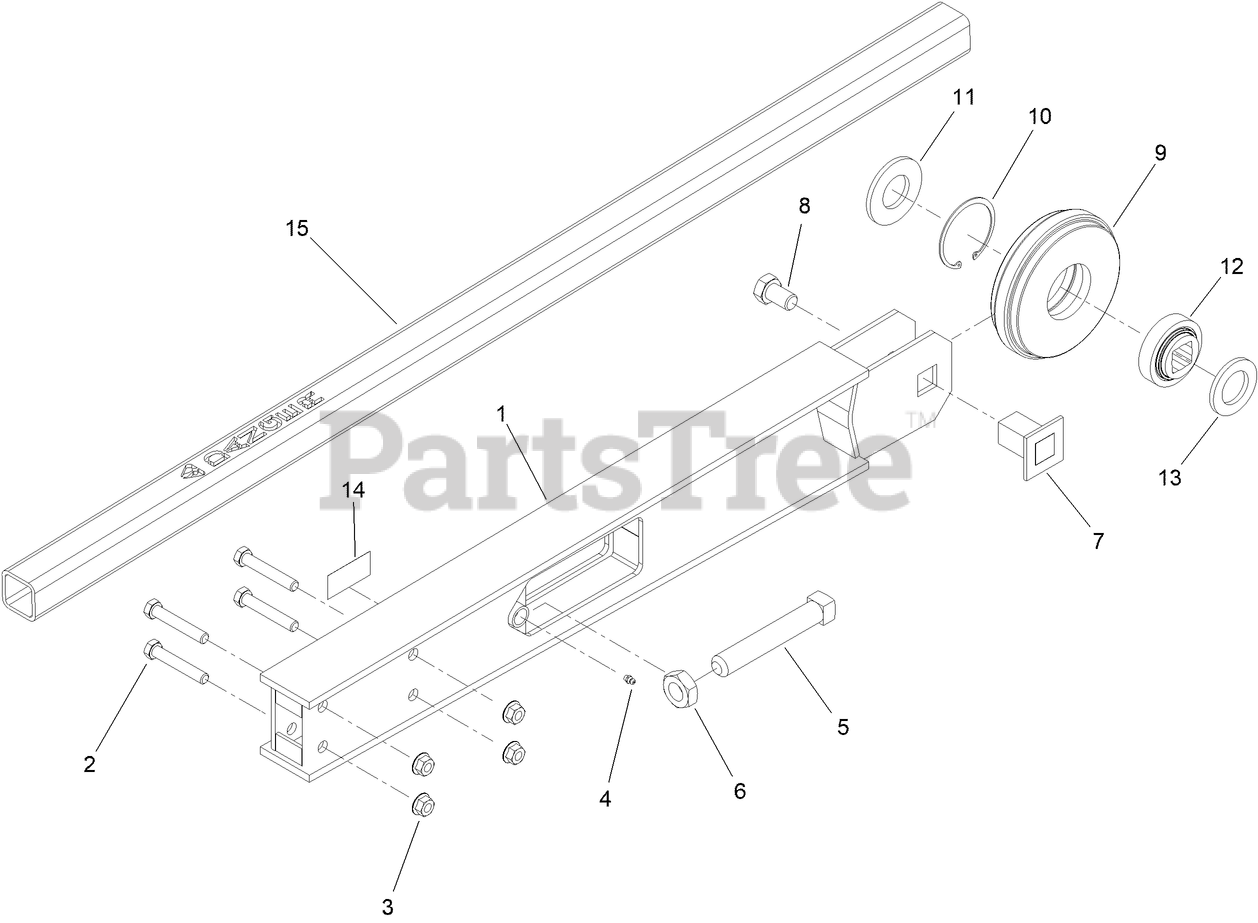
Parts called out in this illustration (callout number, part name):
1	ROLLER BOOM 36.0
2	SCREW-HF
3	NUT-HHF, WHIZ
4	FITTING-GREASE
5	SCREW-SET
6	NUT-HEX
7	IDLER SHAFT
8	LK BOLT
9	TAIL ROLLER
10	INTERNAL SNAP RING 3.149
11	DIRT SHIELD
12	BEARING
13	DIRT SHIELD
14	CHAIN TENSION ISO
15	DANGER RESTRAINT BAR SK 36.0
